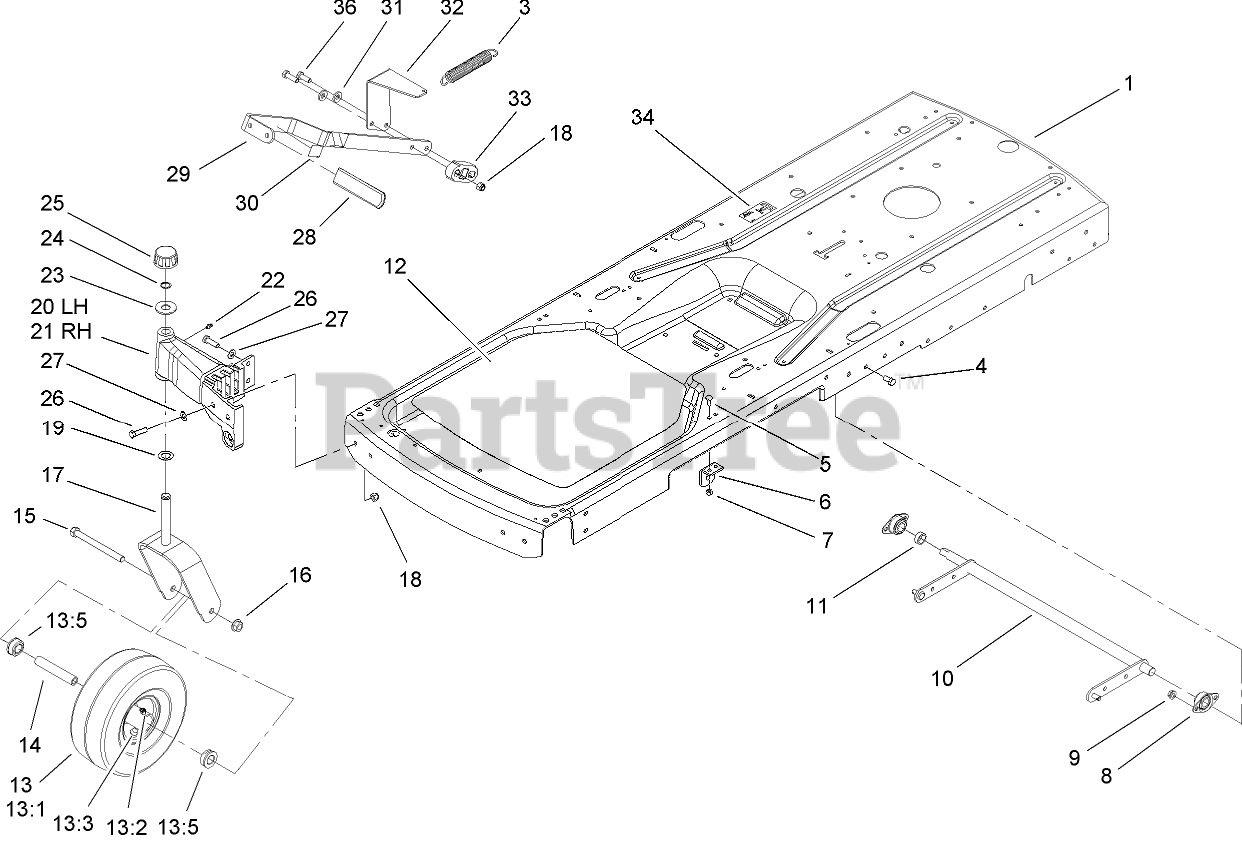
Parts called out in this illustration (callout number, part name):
3	SPRING-EXTENSION
4	SCREW-HH
5	BOLT-CARR
6	BRACKET-LIFT
7	NUT-LOCK, NI
8	BEARING-FLANGE, SIDE
9	NUT-HHF, WHIZ
10	LIFT ARM ASM
11	SPACER
12	PAD-ANTISKID
13	FRONT WHEEL AND TIRE ASM
13:2	FITTING-GREASE
13:3	STEM-VALVE
13:5	BUSHING-FLANGE
14	BUSHING-SPANNER
15	SCREW-HH
16	NUT-HF
17	CASTOR FORK ASM
18	NUT-LOCK, NI
19	WASHER-THRUST
20	CASTER-LH
21	CASTER-RH
22	FITTING-GREASE
23	WASHER-PLAIN
24	RING-RETAINING, EXT
25	CAP-HUB
26	SCREW-HH
27	WASHER-FLAT
28	GRIP-LEVER, LIFT
29	LEVER-LIFT
30	DECAL-HOC
31	WASHER-BELLEVILLE
32	MOUNT-SPRING, FRONT
33	BLOCK-LIFT
34	DECAL-TRANSPORT, CE
36	SCREW-HH
